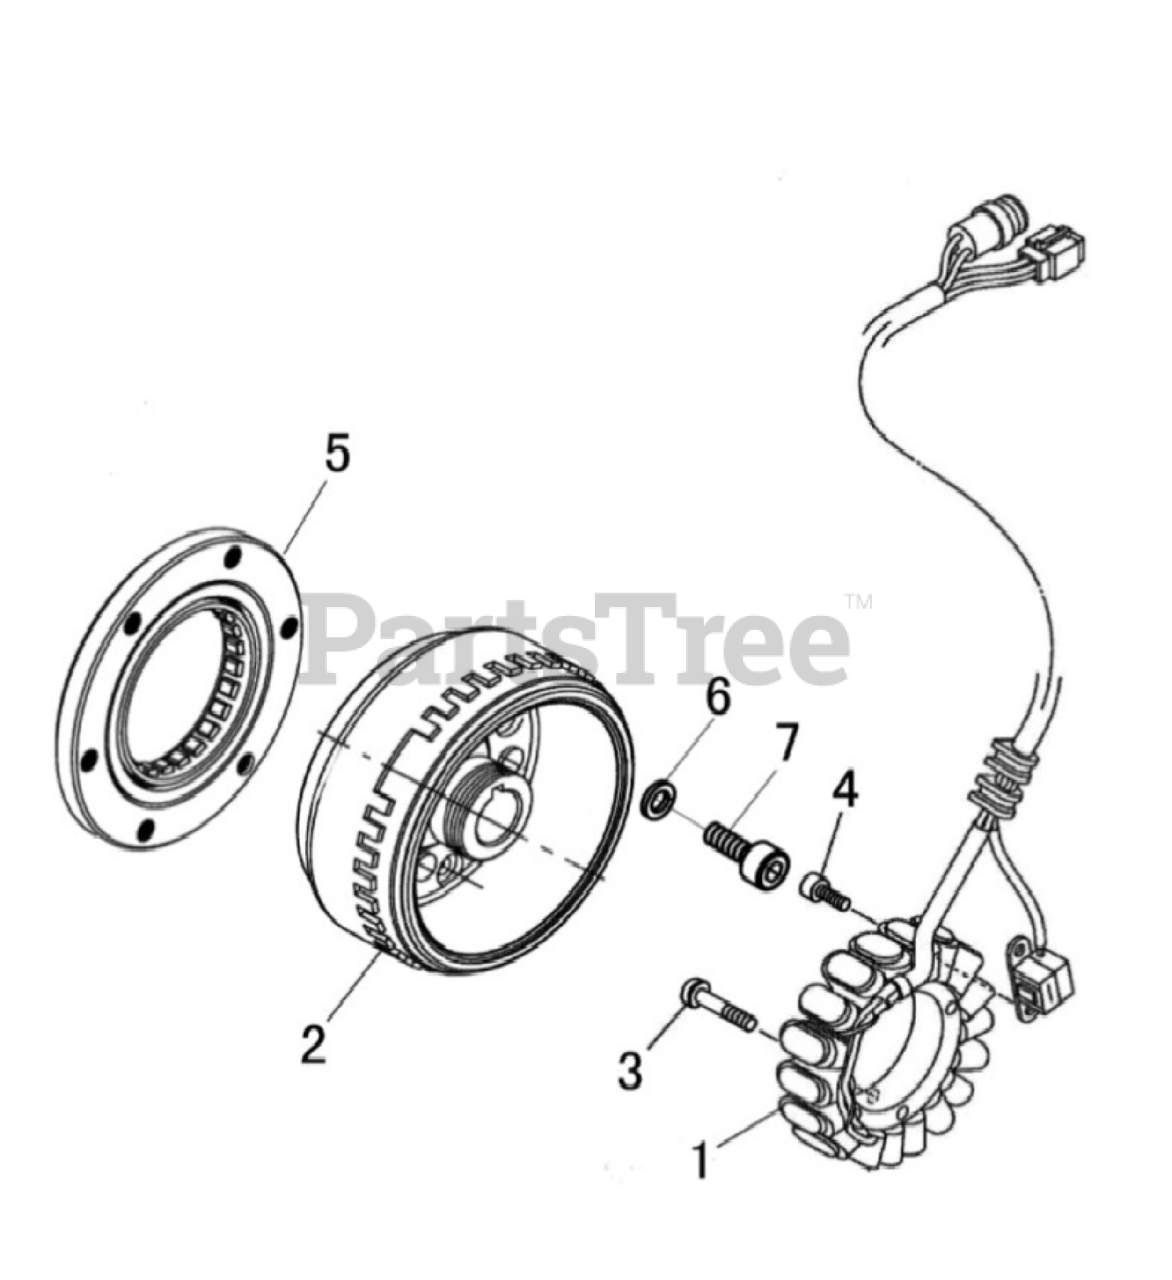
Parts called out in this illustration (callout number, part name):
1	GENERATOR STATOR ASSEMBLY
2	GENERATOR ROTOR ASSEMBLY
3	Hex head bolt & plain washer assemblies M6x30
4	Hex head cap screw M5x12
5	Overrunning Clutch
6	Spring Washer-8
7	Hex head cap screw M8x16
